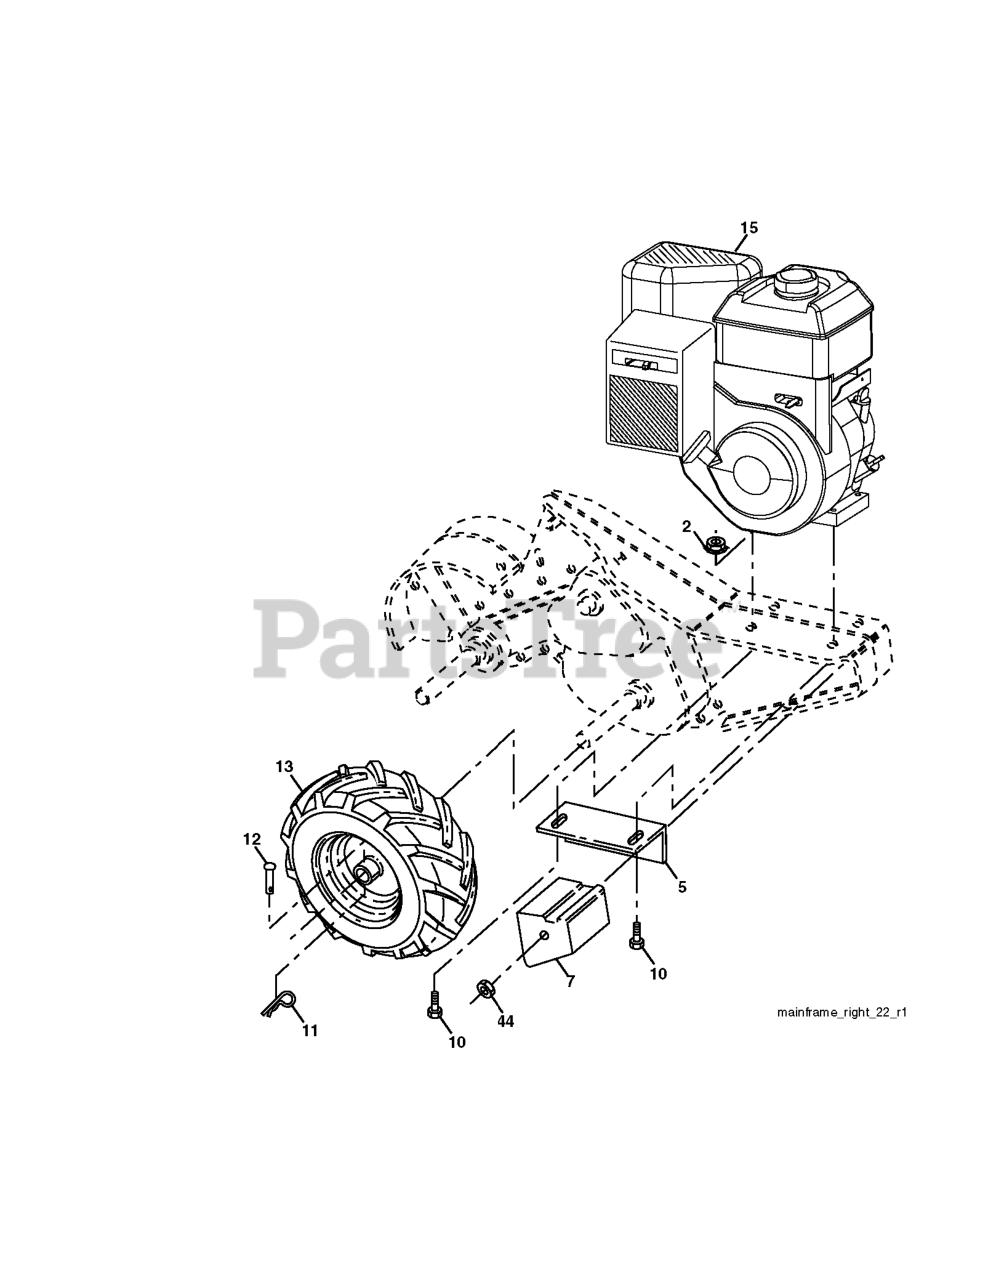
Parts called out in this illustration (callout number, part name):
2	LOCKNUT-FLANGE 5/16-18
5	BRACKET.REINFORCEMENT.RH.BLACK
6	BOLT, HEX 5/16-18X1-3/4
7	COUNTERWEIGHT.RH
10	BOLT
11	RETAINER M
12	RIVET
13	WHEEL 16X4X8.DR TILLER RH.417
